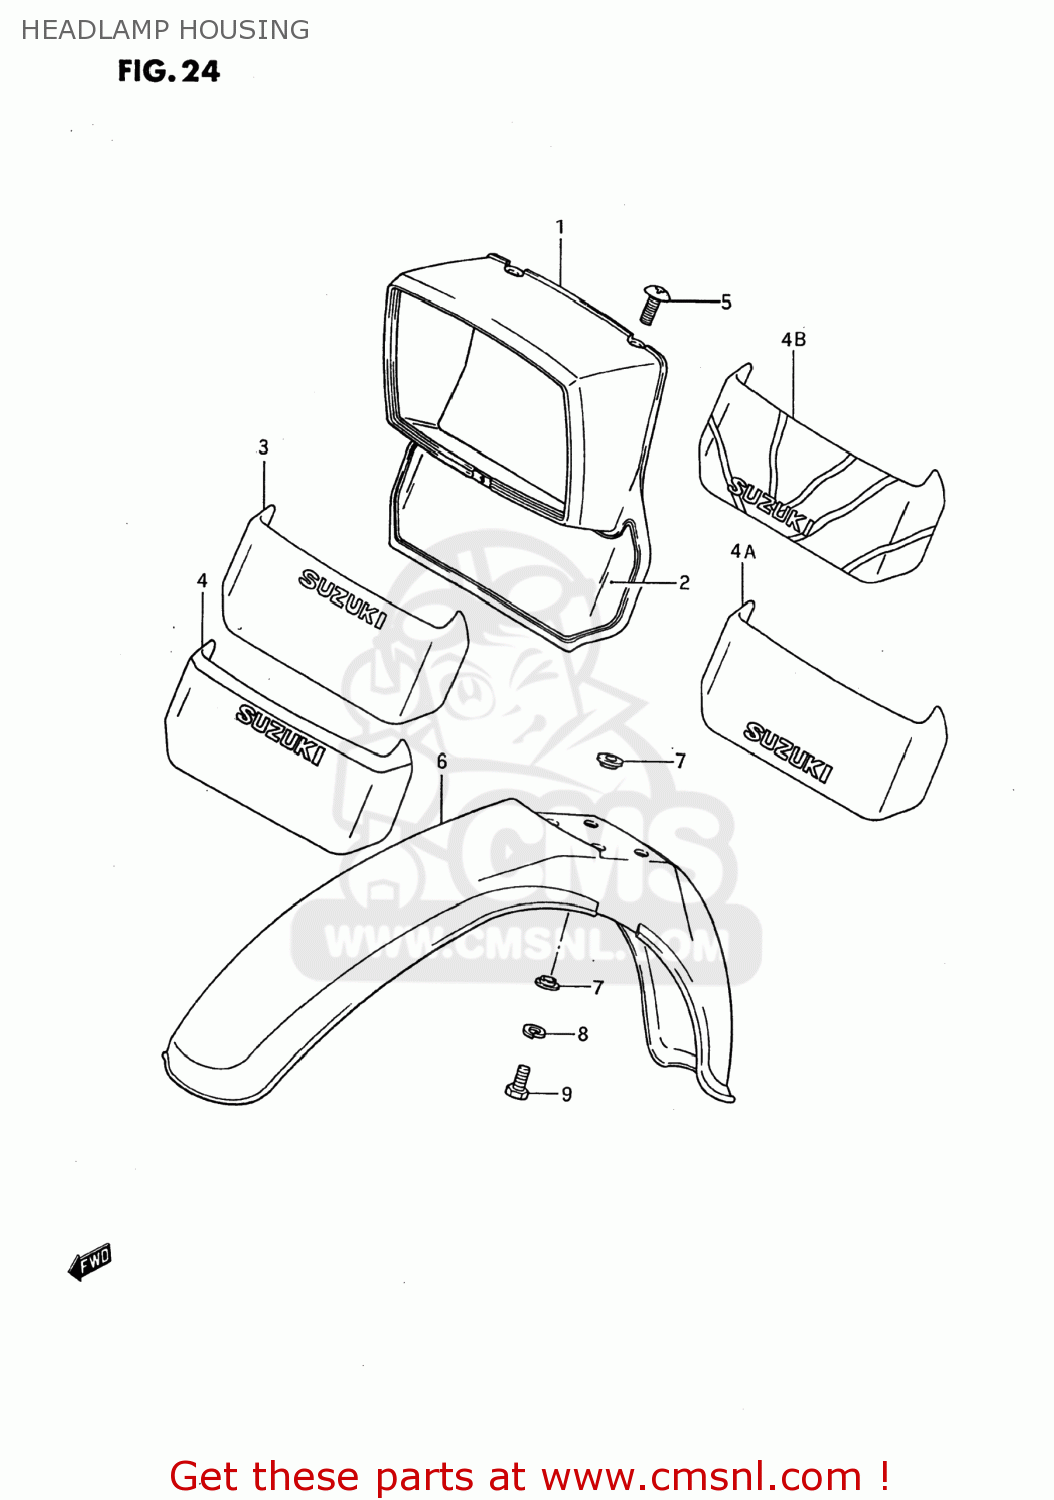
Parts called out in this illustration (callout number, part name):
1	HOUSING,HEADLAMP
2	EMBLEM,FRONT NUMBER PLATE
3	EMBLEM,FRONT NUMBER PLATE
4	TAPE,HEADLAMP HOUSING
4A	TAPE,HEADLAMP HOUSING
4B	TAPE,HEADLAMP HOUSING
5	SCREW 6X12
6	FENDER,FR
7	SPACER
8	WASHER,LOCK
9	BOLT
